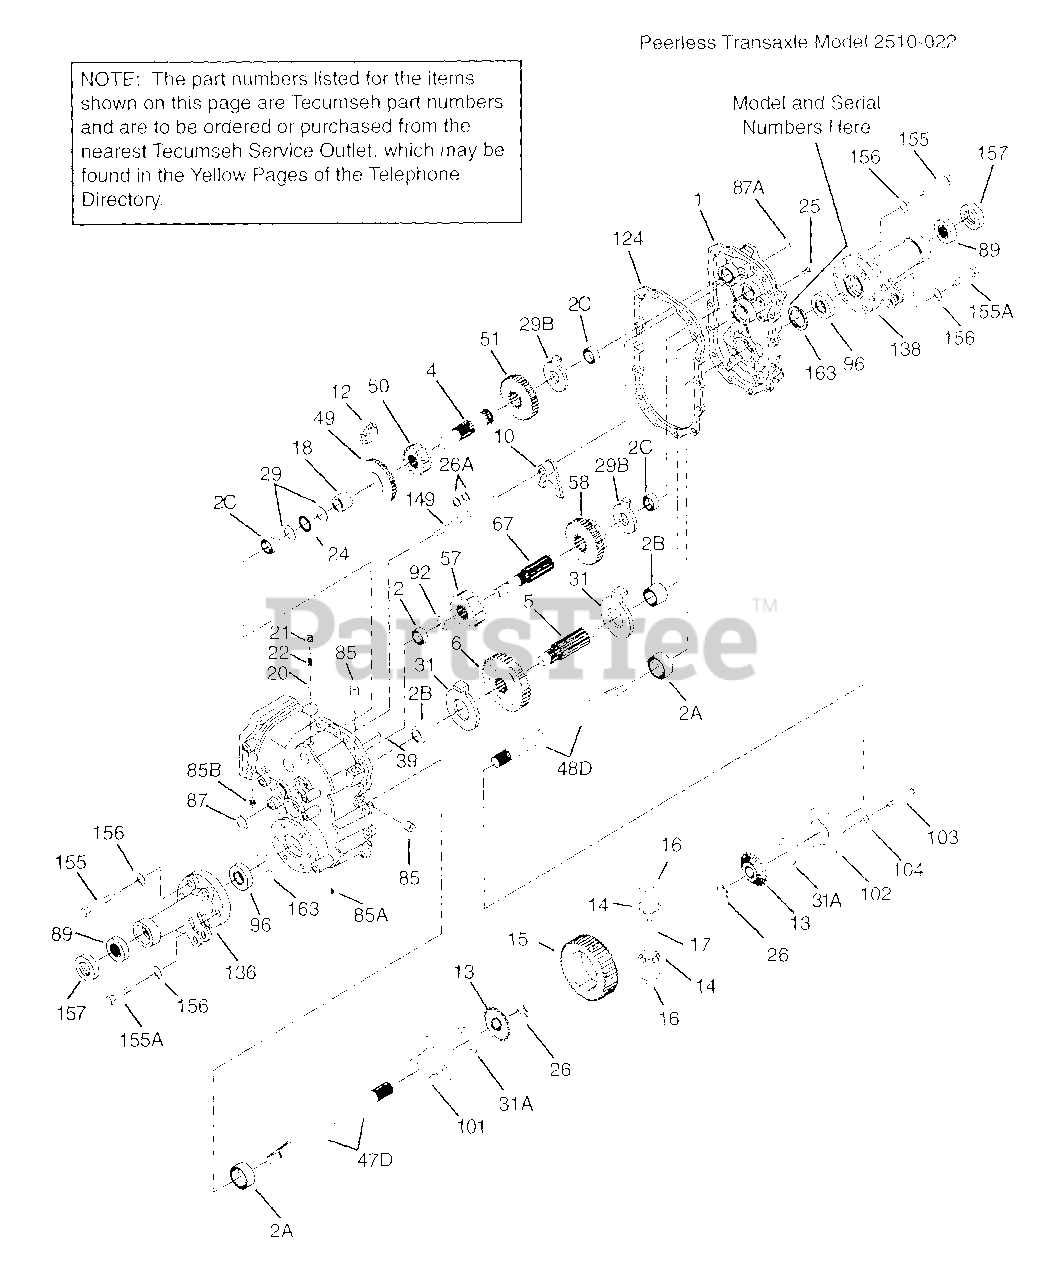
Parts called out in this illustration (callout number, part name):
1	Transaxle Cover
2	Needle Bearing 1" ID
2A	Needle Bearing 2" ID
2B	Needle Bearing 1-1/4" ID
2C	Needle Bearing 1" ID
3	Transaxle Case
4	Countershaft
5	Output Shaft (13 teeth)
6	Spur Gear
10	Shift Fork
12	Bevel Pinion (13 teeth-steel)
13	Bevel Gear (16 teeth-steel)
14	Bevel Pinion (10 teeth-steel)
15	Ring Gear (47 teeth)
16	Drive Block
17	Drive Pin
20	Ball 3/16" dia.
21	Set Screw 1/4-20 x 1/2"
22	Spring Detent
24	Thrust Bearing
25	Screw 5/16-18
26	Retaining Ring
26A	Ext. Retaining Ring .406
29	Thrust Washer
29B	Thrust Washer
31	Thrust Washer
31A	Thrust Washer (.060 thick)
39	Dowel Pin
47D	Axle (19-5/8" long)
48D	Axle (19-3/4" long)
49	Bevel Gear (30 teeth-steel)
50	Spur Gear (16 teeth-steel)
51	Spur Gear (23 teeth-steel)
57	Spur Gear (19 teeth-steel)
58	Shifter Spur Gear (20 & 27 teeth)
67	Shifter & Brake Shaft
85	Pipe Plug 3/8"
85A	Magnetic Drain Plug
85B	Plug 1/8-27
87	Oil Seal 1"
87A	Oil Seal 1/2"
89	Ball Bearing 1-1/8"
92	Thrust Washer
96	Thrust Bearing
101	Differential Carrier
102	Differential Carrier
103	Screw 3/8-16 x 2-3/4"
104	Lockwasher .343 ID
136	Axle Housing (11.2" long)
138	Axle Housing (11.2" long)
149	Shift Rod (High-Low)
155	Screw 1/2-13 x 2-3/4"
155A	Screw 1/2-13 x 1-1/2"
156	Lockwasher
157	Oil Seal 1-1/8"
163	Square Cut Ring
